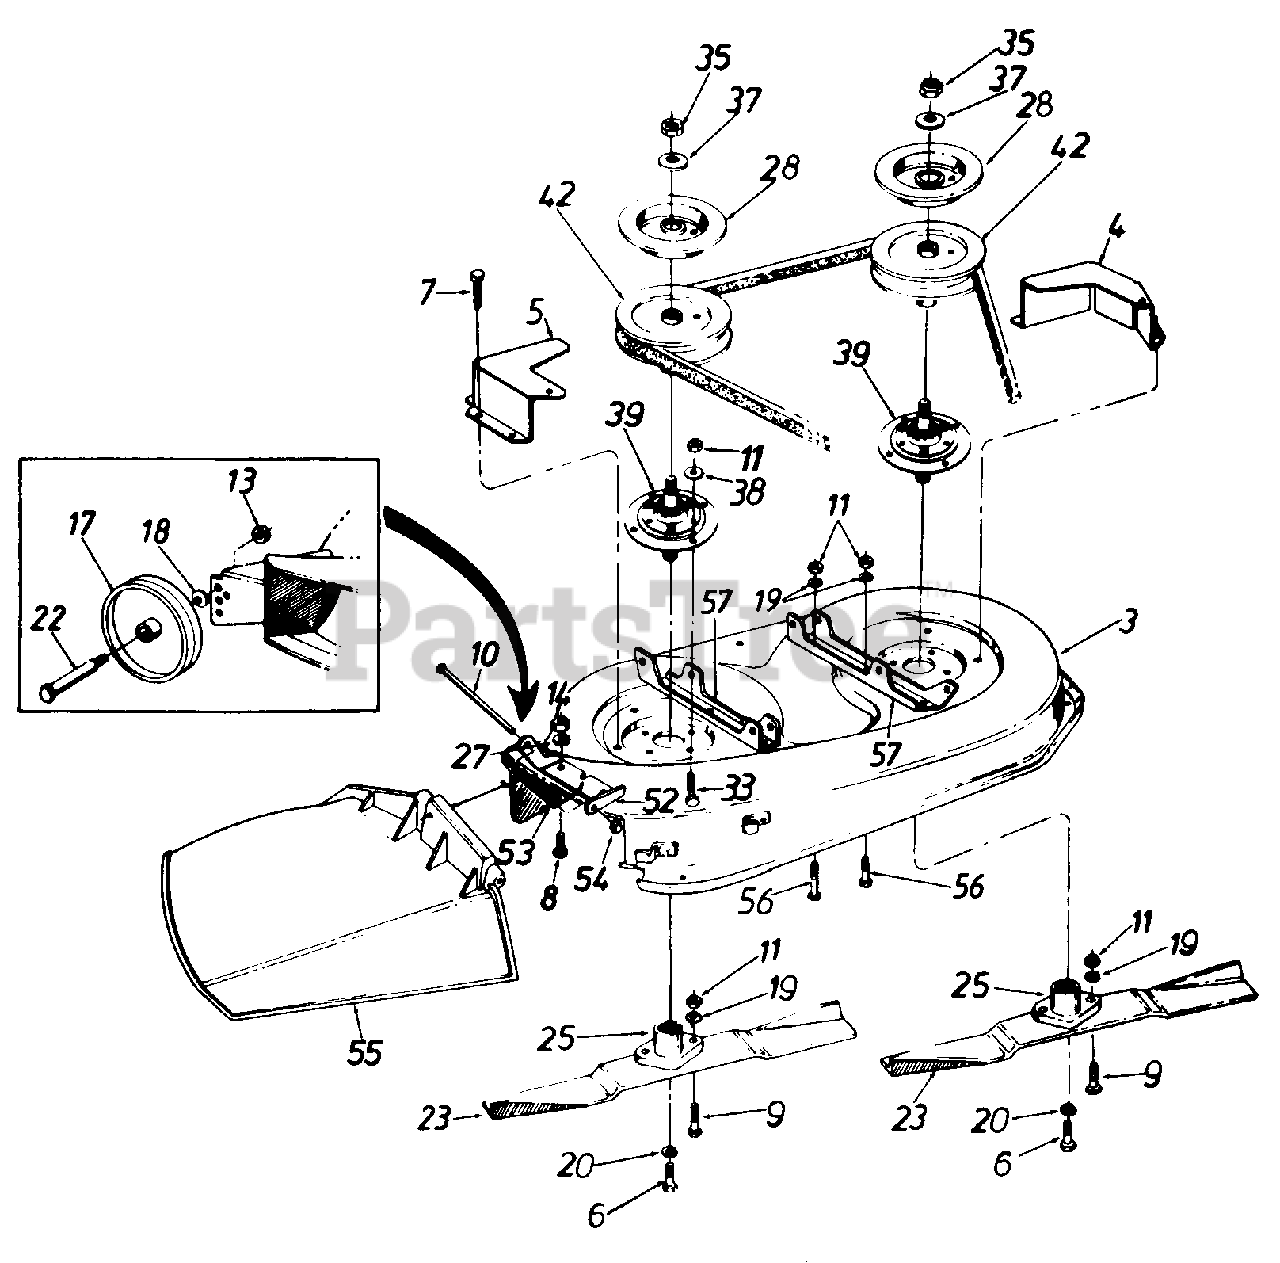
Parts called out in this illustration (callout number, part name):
3	42" Deck Ass'y.
6	Hex Bolt 3/8-24 x 1.0" Lg.
7	Hex Wash. Hd. TT-Tap Scr. 1/4-20 x .5" Lg.
8	Truss Mach. Scr. 1/420 x .75"
9	Hex Bolt Special 5/16-24 x 1.0"
10	Hinge Pin
11	Hex Nut 5/16-24 Thd.
13	Hex Top L-Nut 3/8-16 Thd.
14	Hex Nut 1/4-20 Thd.
17	Deck Wheel-5"
18	Bell-Wash. .40" I.D. x .88" O.D.
19	L-Wash. 5/16" I.D.
20	L-Wash. 3/8" I.D.-H.D.
22	Shld. Bolt .498" Dia. x 1.53"
23	High-Lift Blade
25	Blade Adapter
27	Bell-Wash. 1/4" I.D.
28	Brake Disc
33	Hex Bolt 5/16-24 x .75" Lg.
35	Hex Jam Nut 5/8-18 Thd.
37	L-Wash. 5/8" I.D.
38	L-Wash. 5/16" I.D.
39	Blade Spindle Ass'y. Comp.
42	5 5" Dia. Pulley
52	Hinge Mtg. Brkt.
53	Tcrsion Spring
55	Chute Ass'y. Comp.
56	Hex Bolt 5/16-24 x .75" Lg.
